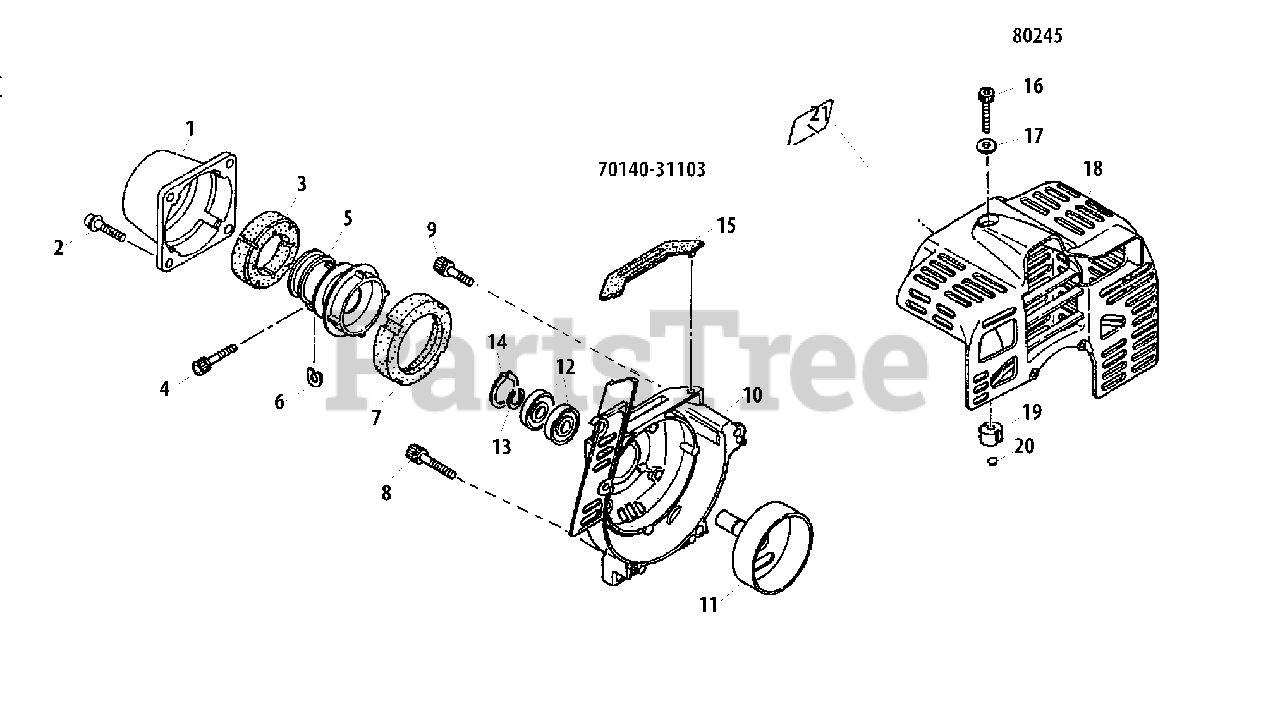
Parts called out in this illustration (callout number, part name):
1	COVER, AV CUSHION (RED)
2	BOLT M5×16
3	CUSHION, FRONT
4	BOLT M5×25
5	JOINT
6	D-WASHER
7	HOLDER, REAR CUSHION
8	BOLT M5×35
9	BOLT M5×16
10	COVER, FAN
11	DRUM, CLUTCH
12	BEARING, BALL 6000ZZ
13	RING, SNAP WR10
14	RING, SNAP Ø26
15	CUSHION
16	BOLT 5×25
17	WASHER 5 MM
18	COVER, ENGINE
19	INSULATOR 5 MM
20	CLIP
21	LABEL - MODEL
70140-31103	COVER ASSY, FAN
80245	ENGINE COVER KIT - RED
